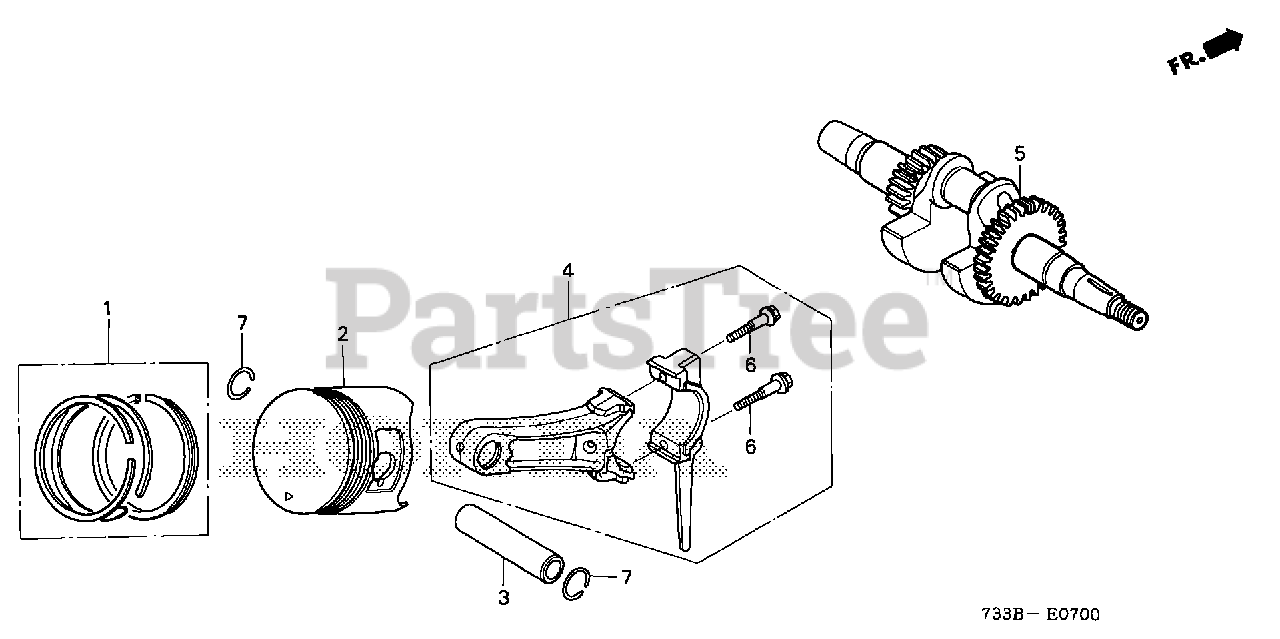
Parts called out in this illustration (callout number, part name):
1	RING SET, PISTON (STD) (TPR)
1	RING SET, PISTON (0.25) (TPR)
1	RING SET, PISTON (0.50) (TPR)
1	RING SET, PISTON (0.75) (TPR)
1	RING SET, PISTON (STD) (RIKEN)
1	RING SET, PISTON (0.25) (RIKEN)
1	RING SET, PISTON (0.50) (RIKEN)
1	RING SET, PISTON (0.75) (RIKEN)
2	PISTON (STD)
2	PISTON (0.25)
2	PISTON (0.50)
2	PISTON (0.75)
2	PISTON (STD) (JIALING-HONDA)
3	PIN, PISTON
4	ROD ASSY., CONNECTING (JLH)
4	ROD ASSY., CONNECTING
5	CRANKSHAFT
6	BOLT, CONNECTING ROD
7	CLIP, PISTON PIN (18MM)
